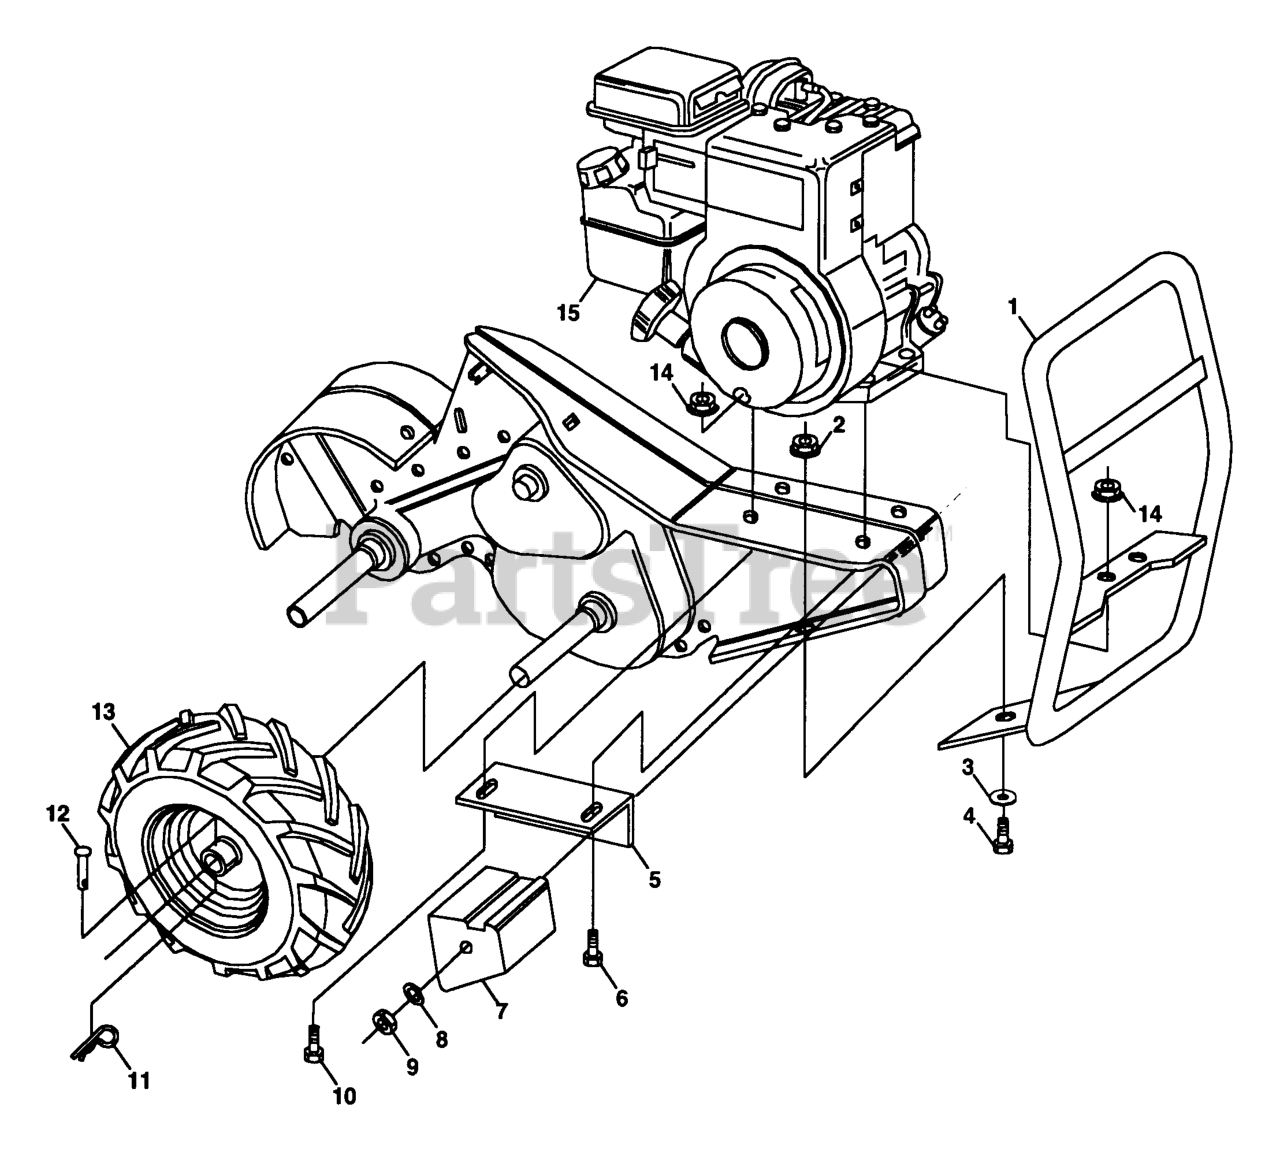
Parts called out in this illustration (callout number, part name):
2	LOCKNUT-FLANGE 5/16-18
3	WASHER
4	BOLT
5	DNO BRACKET RH CRT
6	Bolt, Hex 5/16-18 x 2
7	COUNTERWEIGHT, RH
8	WASHER, LOCK 3/8
9	NUT.HEX.3/8-16UNC
10	BOLT
11	RETAINER M
12	RIVET,DRILLED
13	TIRE.16X4-8.CHEVRON.TILLER
13	RIM
13	VALVE STEM LT
14	NUT
15	Engine
